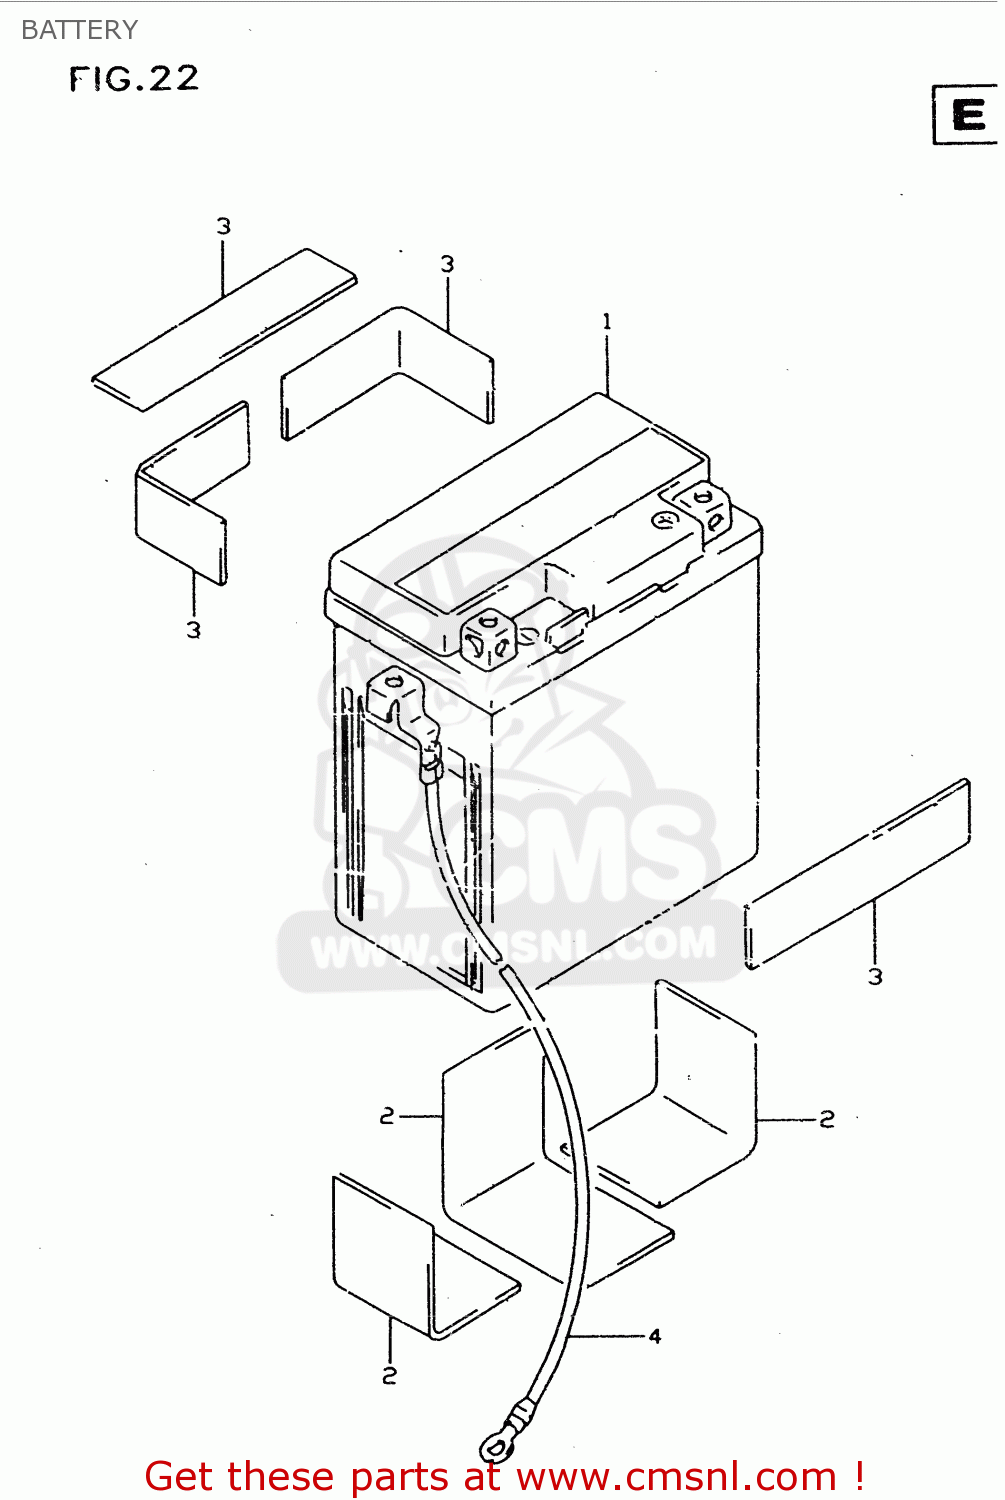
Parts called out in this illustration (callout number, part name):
1	BATTERY ASSY(YTX7L-BS,12V6AH)
2	PROTECTOR(170X95X3.0)
3	PROTECTOR(170X95X3.0)
4	WIRE,BATTERY MINUS LEAD
